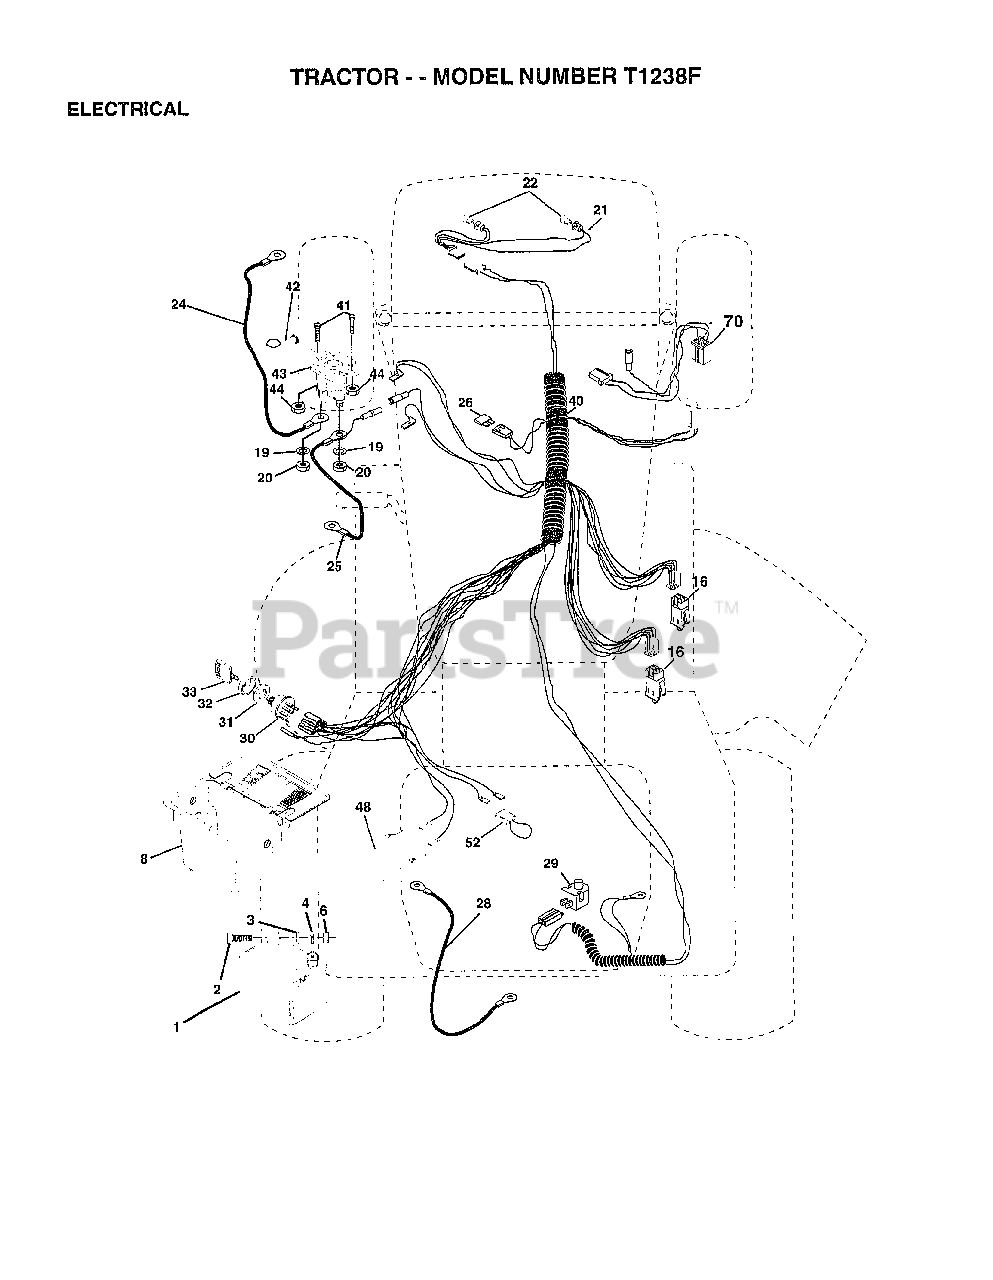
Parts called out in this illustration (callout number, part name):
3	WASHER
4	LOCKWASHER
8	"CASE,BATTERY.MECH"
16	SWITCH INTERLOCK
20	NUT
21	"HARNESS,LIGHT SOC"
22	HEADLAMP BULB
24	"CABLE T, BATTERY"
25	CABLE.BTRY.6GA.RD
26	FUSE HYT
28	CABLE T
29	SWITCH SEAT
30	SWITCH IGN 4POS
31	NUT IGNITION
32	COVER KEY SWITCH
33	KEY
40	HARNESS-IGNITION
41	BOLT HXHD FIN
44	NUT HXKEP 1/4X20
48	ADAPTER AMMETER
52	PROTECTION LOOP
70	HARNESS ENG DUAL
